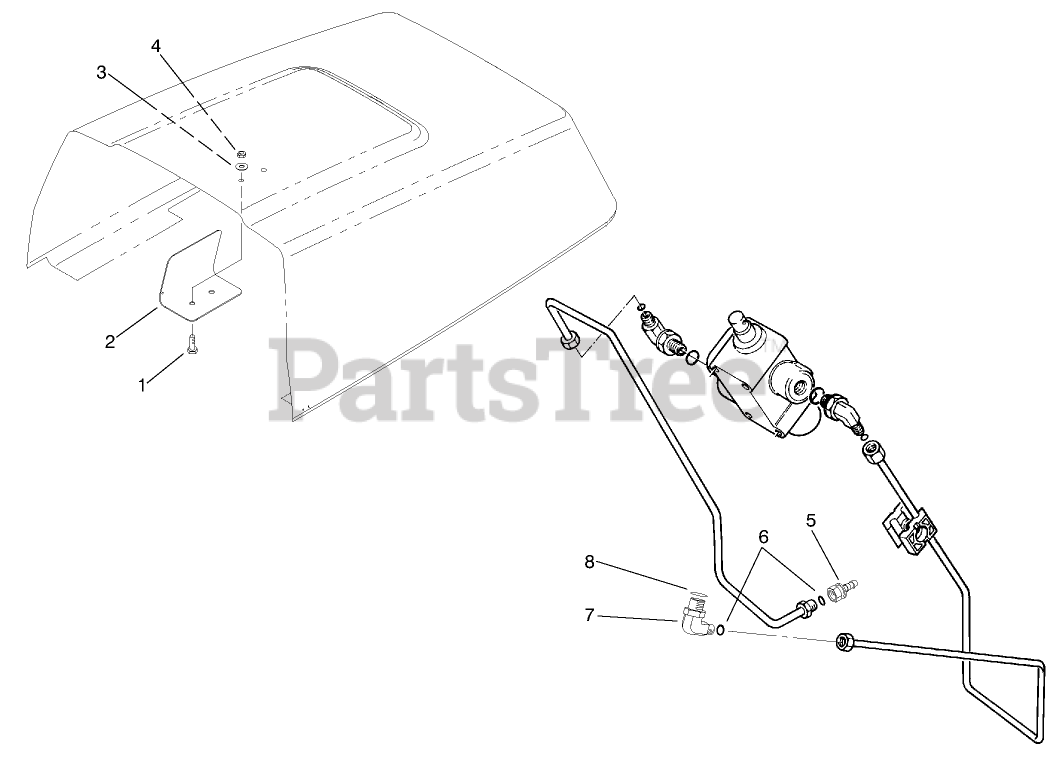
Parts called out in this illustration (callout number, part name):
1	SCREW-HH
2	Plate-Skid
3	WASHER-FLAT
4	NUT-LOCK, NI
5	FITTING-HYD
6	O-RING
7	FITTING-ELBOW, 90 DEG
8	O-RING
